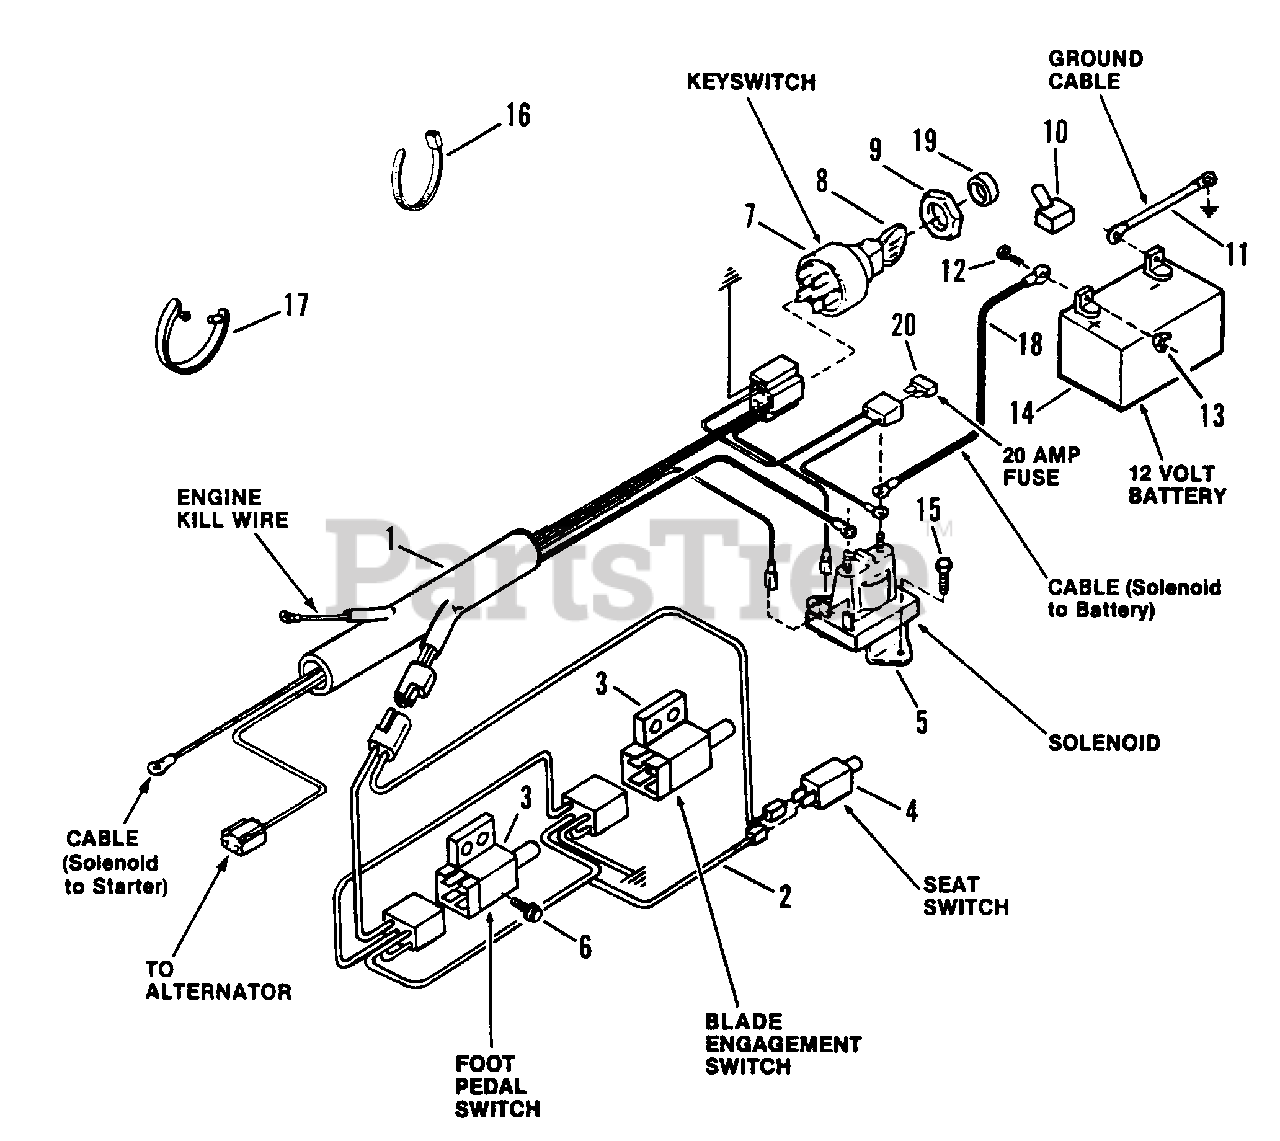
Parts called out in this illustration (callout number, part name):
1	HARNESS, Wiring (B. & S.)
2	HARNESS, Interlock
3	SWITCH, Clutch & PTO
4	SWITCH, Seat
5	SOLENOID
6	SCREW, #10-24 x 1/2" Hex Washer Self-Tap (Torx)
7	SWITCH, Key
8	KEY, Switch (With Cover)
9	NUT, 5/8-32 Hex
10	COVER, Positive Terminal
11	CABLE, Negative
12	BOLT, 1/4-20 x 3/4" Carriage
13	WING-NUT, 1/4-20
14	KIT, Battery
15	SCREW, 1/4-20 x 1/2" Self-Tapping
16	TIE, Cable
17	TIE, Wire
18	CABLE, Positive
19	BEZEL
20	FUSE, 20 Amp
